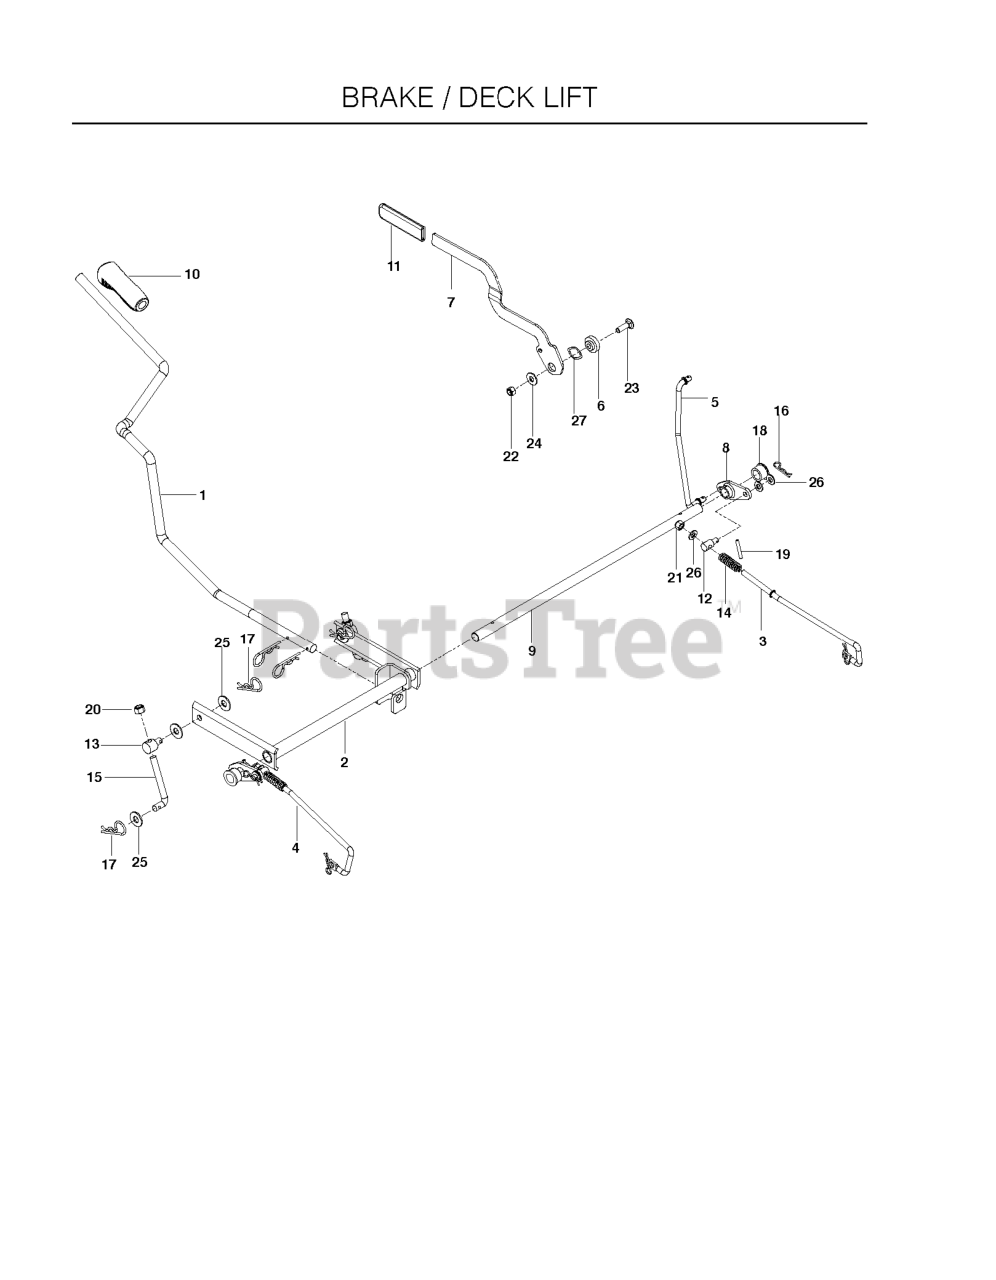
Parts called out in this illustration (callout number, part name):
1	ARM, LIFT HANDLE, BLK
2	WLDMT.LIFT.SHAFT.BLACK
3	LINKAGE, EZT BRAKE RT
4	LINKAGE, EZT BRAKE LT
5	LINKAGE, BRAKE, UPPER
6	BRAKE ARM PIVOT
7	HANDLE, BRAKE, BLK
8	BELLCRANK, BRAKE
9	ROD, BRAKE (2 2)
10	GRIP.LEVER.5625.ID
11	GRIP BRAKE HANDLE
12	BRAKE SWIVEL
16	HAIRPIN #2
17	HAIRPIN #4
18	PLASTIC BUSHING
19	ROLL PIN 3/16 X 1-1/4 ZD
20	NUT 3/8-16 NYLOC
21	NUT 5/16 NYLOC
22	NUT HEX 3/8-16 NYLON, THIN
23	RHSNB 3/8-16 X 1-1/4
24	WASHER, 7/16 DISC SPRING
25	WASHER 3/8 FLAT
26	FLAT WASHER 5/16 SAE
27	WASHER, .825 X 1.087, WAVE
